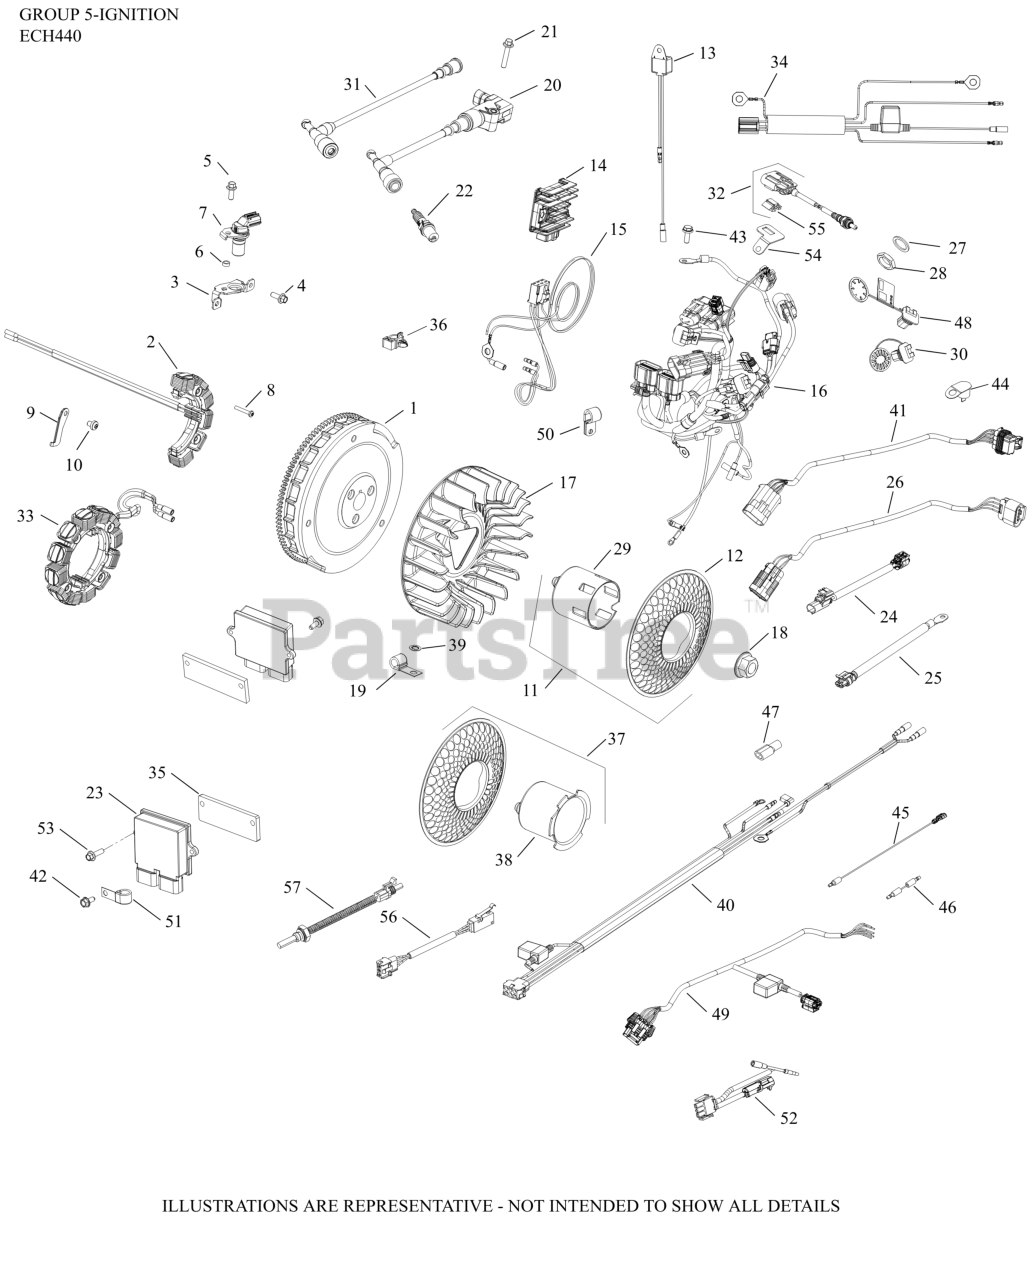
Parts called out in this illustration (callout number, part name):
1	FLYWHEEL ASSY, ELECTRIC START 18 AMP
3	BRACKET, CRANK SENSOR
5	SCREW, HEX FLANGE
7	SENSOR, SPEED
8	SCREW, STATOR MOUNTING
9	BRACKET, STATOR WIRE
10	SCREW, COIL BRACKET
13	CONTROL, OIL ALERT UNIT
14	REG/RECT-25 AMP W/VOLT PROT.
16	HARNESS, WIRING ASSEMBLY
17	FAN, FLYWHEEL
18	NUT, FLYWHEEL
20	COIL, IGNITION - EFI
21	SCREW, HEX FLANGE (M6)
22	PLUG, SPARK
33	STATOR ASSEMBLY, 18A
35	INSULATOR, ECU
37	GRASS SCREEN ASSEMBLY
42	SCREW, HEX FLANGE (M6)-USE 25 086 433-S
51	CLIP, CABLE (KM)
53	SCREW, FLG M6x1.0x20
54	BRACKET, OXYGEN SENSOR
55	CLIP, O2 SENSOR
